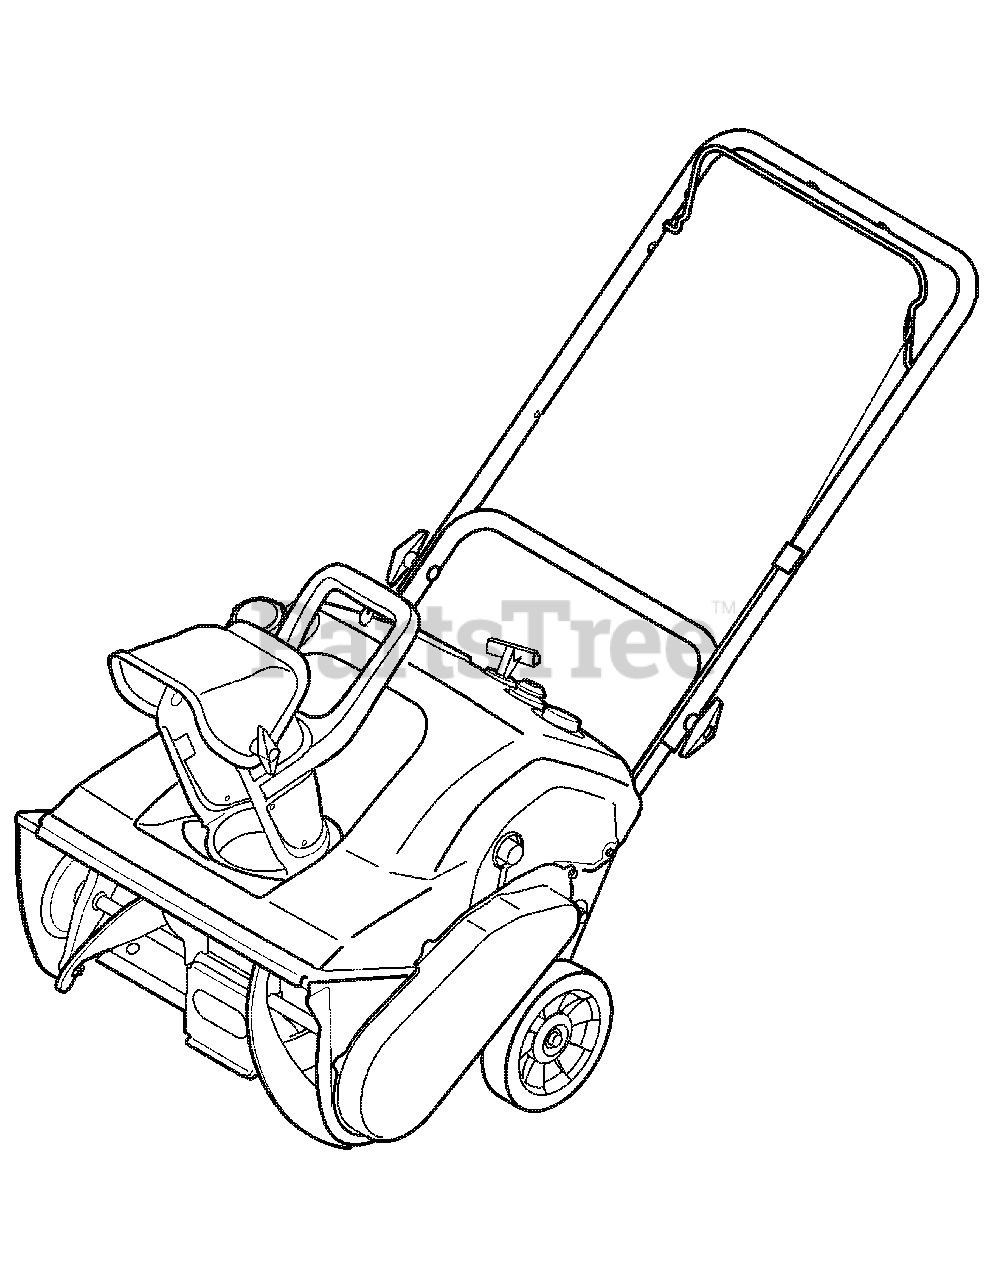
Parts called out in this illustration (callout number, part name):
NA	Extension Cord
NA	Snow Removal Tool
NA	Slide Shoe
NA	Shear Pin
NA	Bow Tie Cotter Pin
NA	Lamp
NA	Wheel Drive Belt
NA	Friction Wheel Assembly
NA	Friction Wheel Rubber
